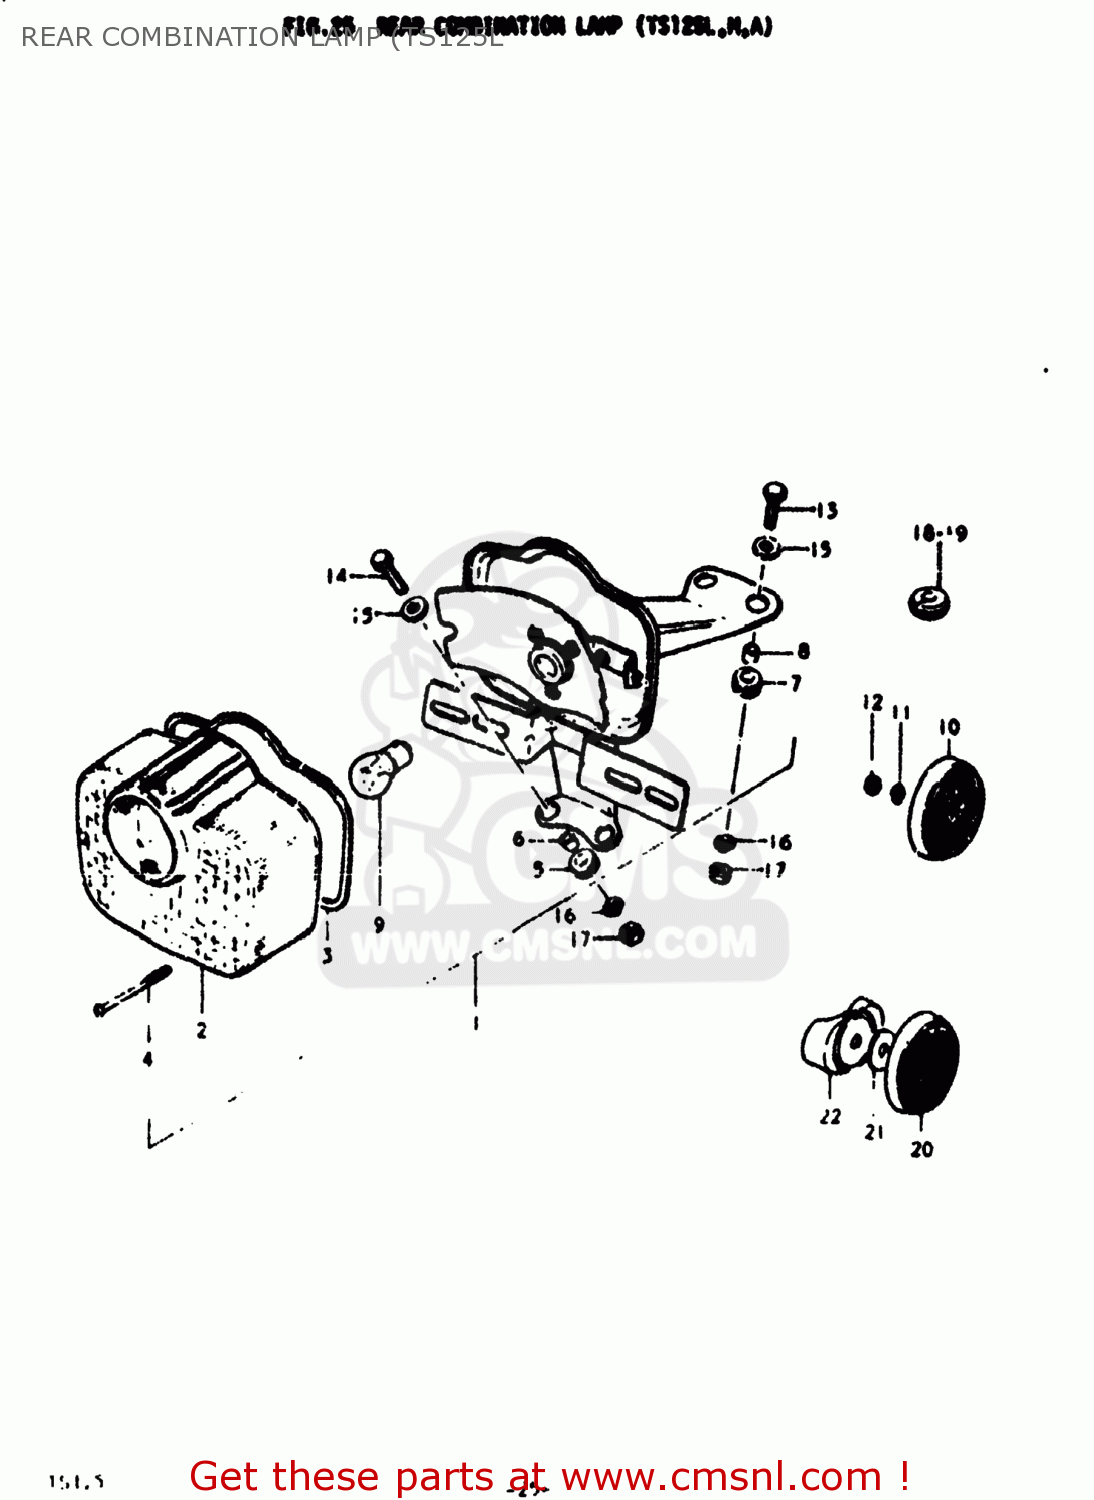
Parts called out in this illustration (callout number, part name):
1	LAMP ASSEMBLY,REAR COMBINATION
2	LENS,REAR COMBINATION LAMP
3	GASKET (NAS)
4	SCREW
5	CUSHION
6	SPACER,REAR COMBINATION LAMP
7	CUSHION
8	SPACER,REAR COMBINATION LAMP
9	BULB(6V32/3CP,STANLEY)
10	REFLECTOR,REFLEX
11	LOCK WASHER
12	NUT
13	BOLT
14	BOLT
15	WASHER
16	LOCK WASHER
17	NUT
18	GROMMET
19	GROMMET
20	REFLEX REFLECTOR ASSEMBLY
21	WASHER (6.5X20X1.2)
22	SPACER
